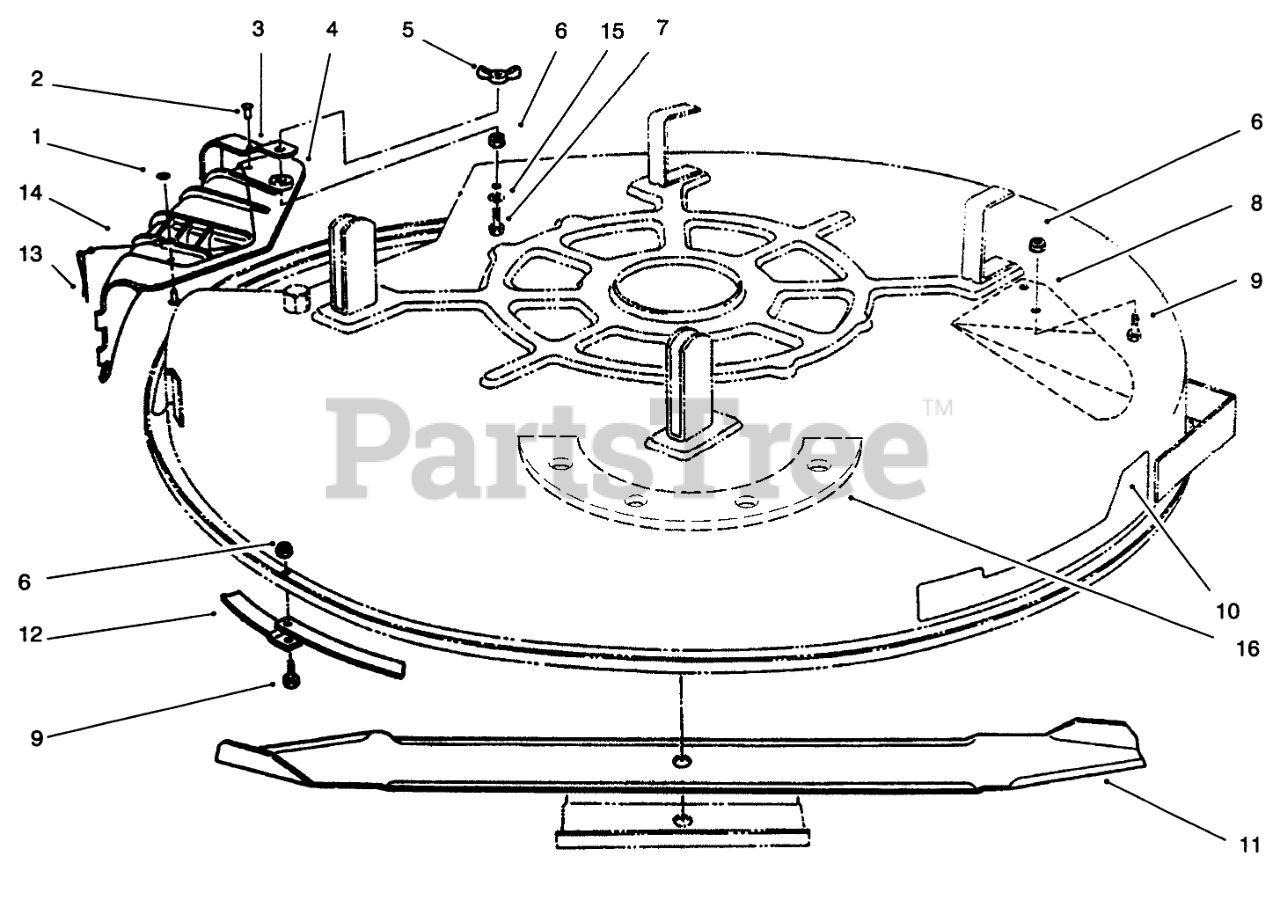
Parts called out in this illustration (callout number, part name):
1	WASHER-PLAIN
2	RIVET-BLIND
3	Brace-Cover, Rear
4	Assy.-Cover, Discharge (Incl. Ref. #1-3, 13 & 14)
5	NUT-WING
6	NUT-LOCK, NI
7	SCREW-HH
8	Kicker
9	SCREW-HH
10	DECAL-RECYCLER
11	BLADE-RECYCLER
12	RING-DECK
13	PIN-LOCKING, CHUTE
14	LANYARD
15	WASHER-PLAIN
16	Ring-Spindle
